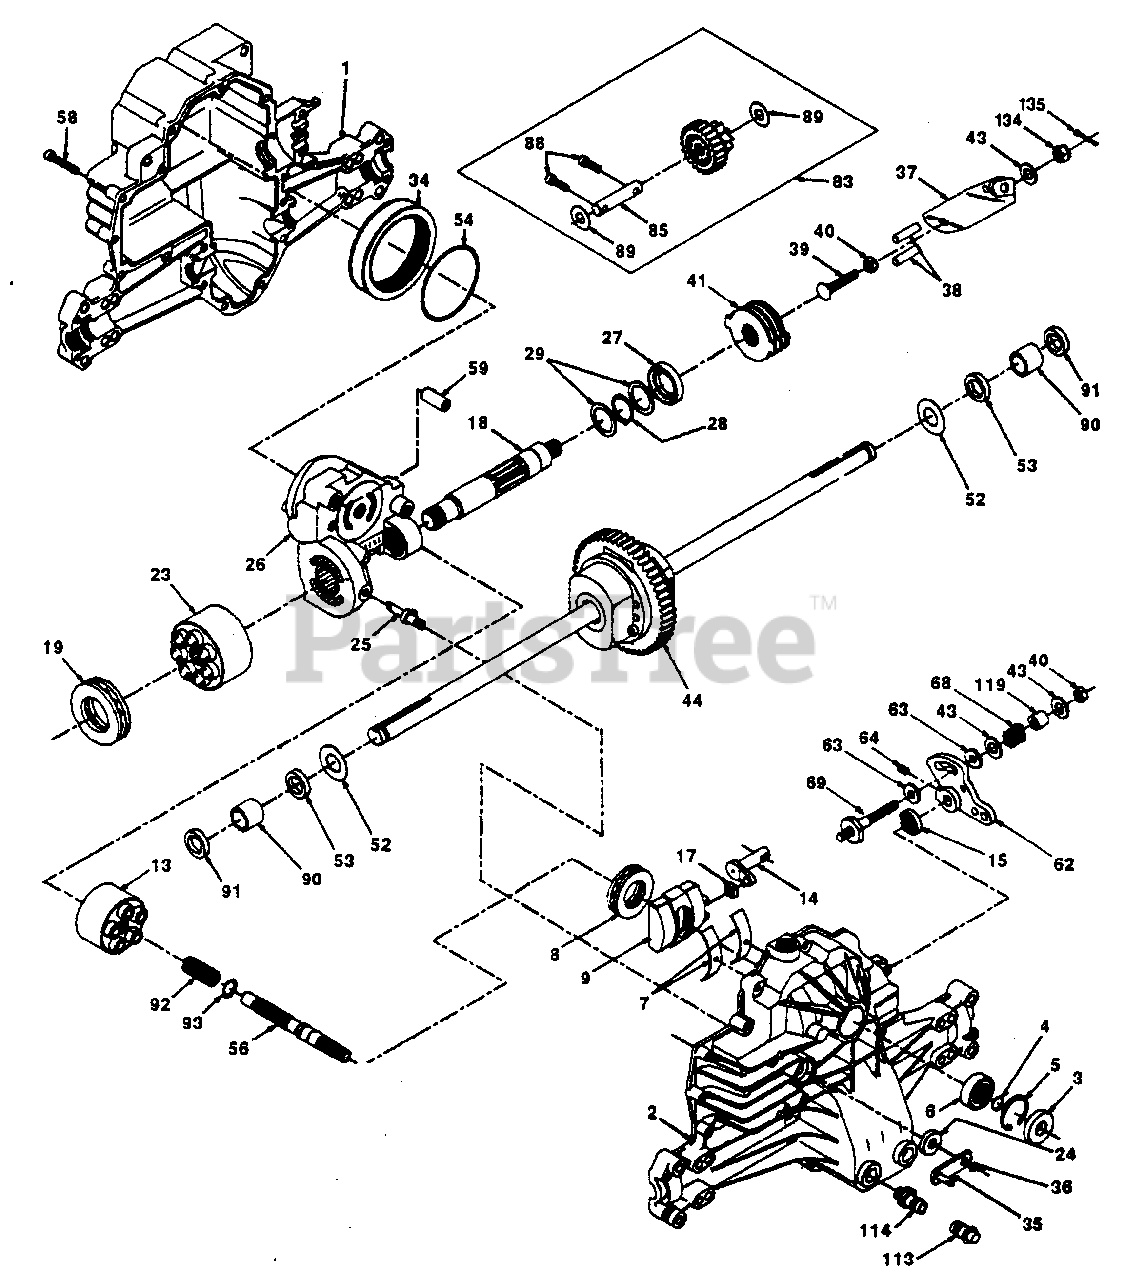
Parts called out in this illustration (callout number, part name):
1	Housing, Lower (AYP part number)
2	Assembly, Upper Housing (AYP part number)
3	Seal, Lip (AYP part number)
4	Ring, Wire Retaining (AYP part number)
5	Ring, Retaining (AYP part number)
6	Bearing, Shaft Ball (AYP part number)
7	Bearing, Cradle (AYP part number)
8	Bearing, Thrust 30 x 52 x 13 (AYP part number)
9	Swashplate, Variable (AYP part number)
13	Block, Cylinder Assembly (AYP part number)
14	Arm, Trunnion (AYP part number)
15	Seal, Lip (AYP part number)
17	Guide, Slot (AYP part number)
18	Shaft, Motor (AYP part number)
19	Bearing, Thrust 42 x 68 x 16 (AYP part number)
23	Block, Cylinder Assembly (AYP part number)
24	Seal, Lip 10 x 25 x 7 (AYP part number)
25	Actuator, Bypass (AYP part number)
26	Center Section Assembly Kit (AYP part number)
27	Seal, Lip 26 x 42 x 8 (AYP part number)
28	Ring, Retaining (AYP part number)
29	Washer 26 x 35 x 1 (AYP part number)
34	Oil Filter Element (AYP part number)
35	Arm, Bypass (AYP part number)
36	Ring, Retaining (AYP part number)
37	Arm, Actuating (AYP part number)
38	Pin, Actuating (AYP part number)
39	Bolt 5/16-24 x 1-3/4 (AYP part number)
40	Locknut, Hex 5/16-24 UNJC (AYP part number)
41	Brake Rotor/Stator Kit (AYP part number)
43	Washer 7/16 x 7/8 x .060 (AYP part number)
44	Differential Assembly (AYP part number)
52	Washer 3/4 x 1.5 x .03 (AYP part number)
53	Seal .75 x 1.25 x .250 (AYP part number)
54	O-Ring .103 x 2.987 ID (AYP part number)
56	Shaft, Input (AYP part number)
58	Bolt 1/4-20 x 1.38 (AYP part number)
59	Pin .5 OD x .43 ID x .750 (AYP part number)
62	Arm, Control (AYP part number)
63	Puck, Dampener (AYP part number)
64	Set Screw (AYP part number)
68	Spring (AYP part number)
69	Stud 5/16-24 (AYP part number)
83	Jack Shaft Assembly (AYP part number)
85	Jack Shaft (AYP part number)
88	Capscrew (AYP part number)
89	Washer (AYP part number)
90	Sleeve Bearing (AYP part number)
91	Seal, Wiper (AYP part number)
92	Spring, Block (AYP part number)
93	Washer, Block Thrust (AYP part number)
113	Cap, Vent Assembly (AYP part number)
114	Fitting, O-Ring Assembly (AYP part number)
119	Spacer (AYP part number)
134	Nut, Castle 5/16-24 (AYP part number)
135	Pin, Cotter (AYP part number)
